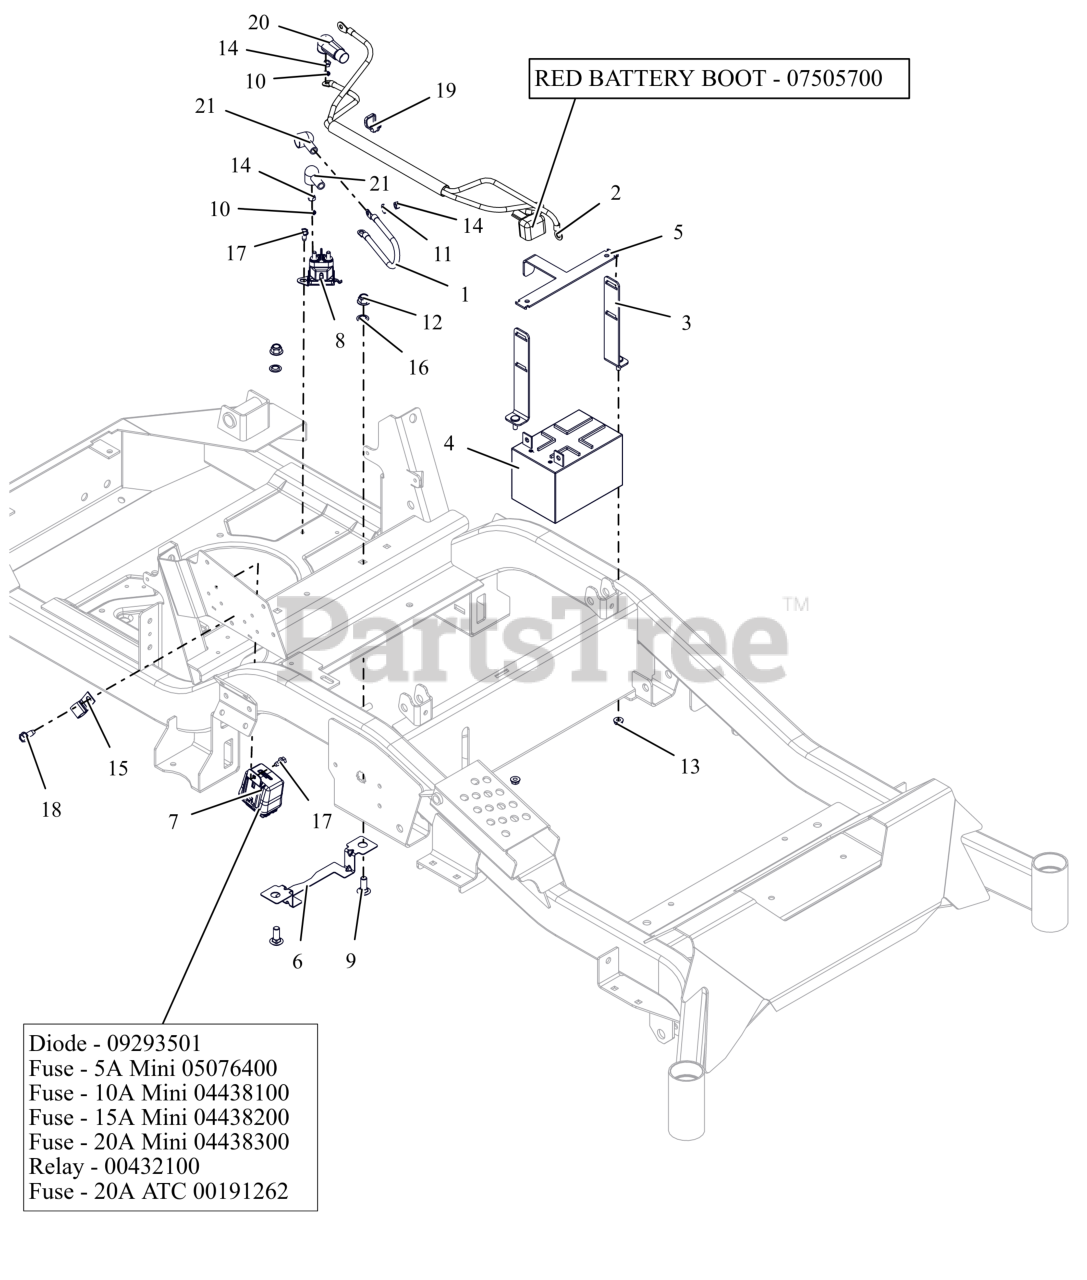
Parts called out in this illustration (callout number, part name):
1	CABLE, POS W/(2)1/4 RING 9.0LG
2	HARNESS, BATTERY HD
2	INSULATOR
3	WMT,BATTERY MOUNT HOLD DOWN
4	BATTERY, 12V 12A-190CCA
5	BRKT, BATTERY TIE DOWN
6	GUARD, ELECTRICAL HARNESS
7	HARNESS, WIRE
7	DIODE, CONNECTOR SHELL
7	FUSE, 5 AMP MINI-ATC
7	FUSE,10 AMP MINI-ATC
7	Fuse, 15 AMP MINI-ATC
7	FUSE,20 AMP MINI ATC
7	RELAY,MICRO5 TERML W/RESISTOR
7	FUSE, 20 AMP BLADE S/O
8	SOLENOID, STARTER (SEALED)
9	BLT, RHSN .38-16X1.00 G5 ZCC
10	WSHR,LK-EXT.262X.502X.026 ZCC
11	WSHR,LK-REG .312X.078 ZCC
12	NUT,NYL-FLG .38-16 GF ZCC
13	NUT-LK-TOP-FLG .250-20 GF ZCC
14	NUT-STD M6-1.0 ZCC
15	J-CLAMP
16	NUT-PUSH .38 DIA. PAL ZINC
17	SCR-TAP .25-20X.50 HWH ZCC
18	SCR,TAP .312-18X.75 HWH TR ZCC
19	CABLE TIE W/ TREE (.25 HOLE)
20	BOOT, .65ID POS
21	BOOT, EYELET TERMINAL
